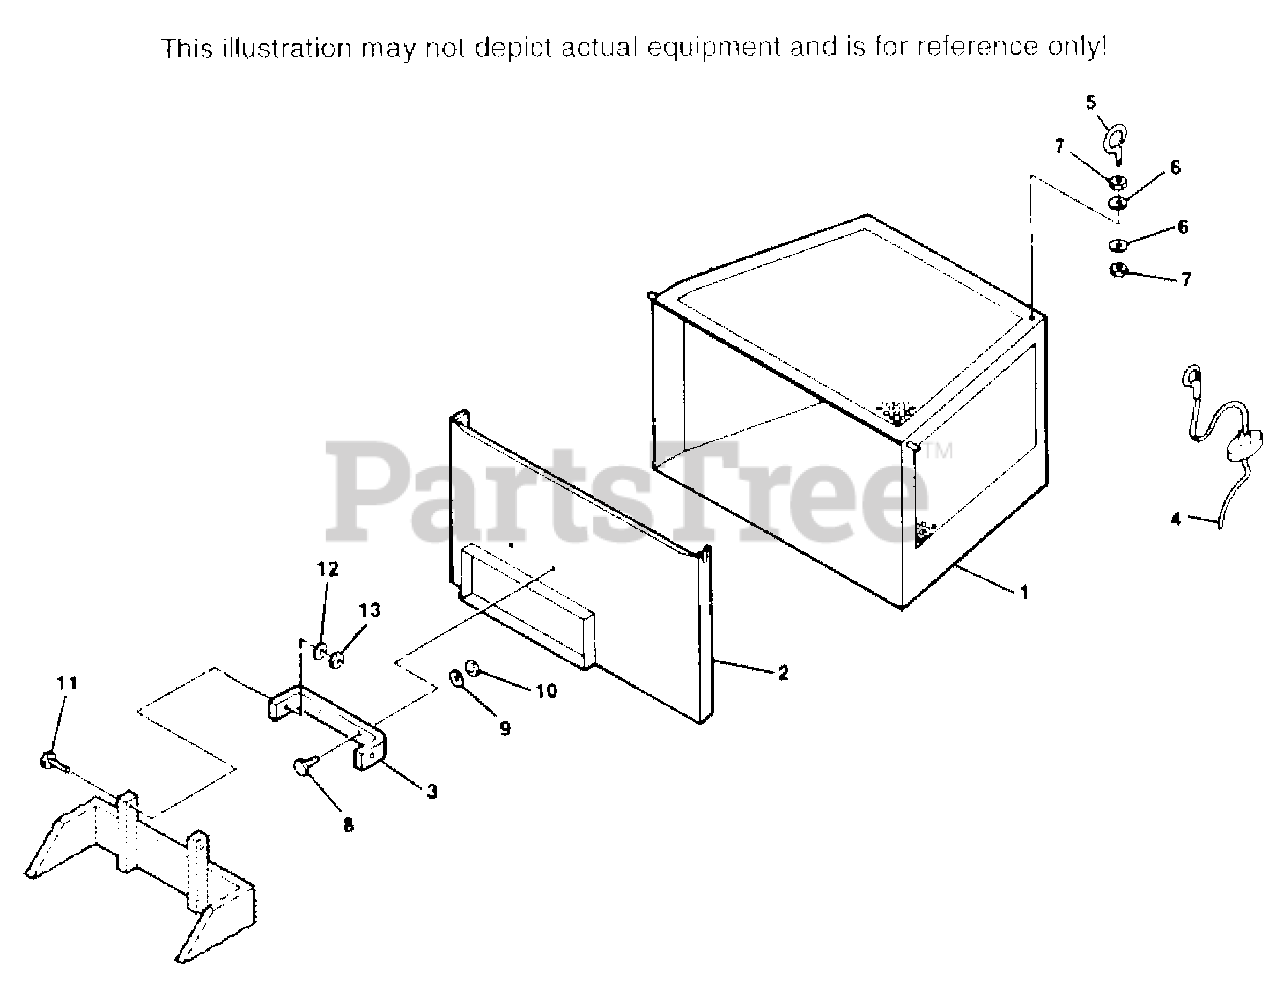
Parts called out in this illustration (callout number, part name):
1	CATCHER BOX
2	SUPPORT COVER
3	MOUNTING BRACKET
4	PULL ROPE ASSEMBLY
5	EYEBOLT
